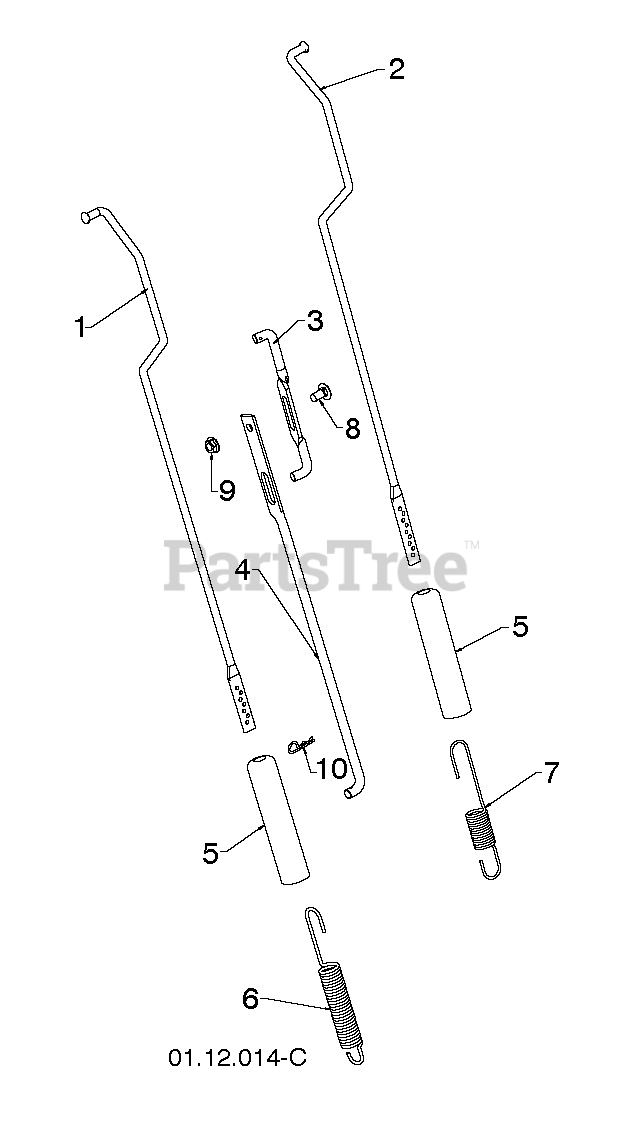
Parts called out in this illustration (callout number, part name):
1	ROD.IMPELLER
2	ROD.TRACTION
3	ROD.SHIFTER.TOP.HYD
4	ROD, LOWER, SPEED CONTROL
5	SLEEVE, SPRING
6	SPRING.CONTROL.ROD.SNOW
7	SPRING.TRACTION.ROD.SNOW
8	BOLT
9	NUT.FLANGE.5/16
10	SPRING RETAINER
